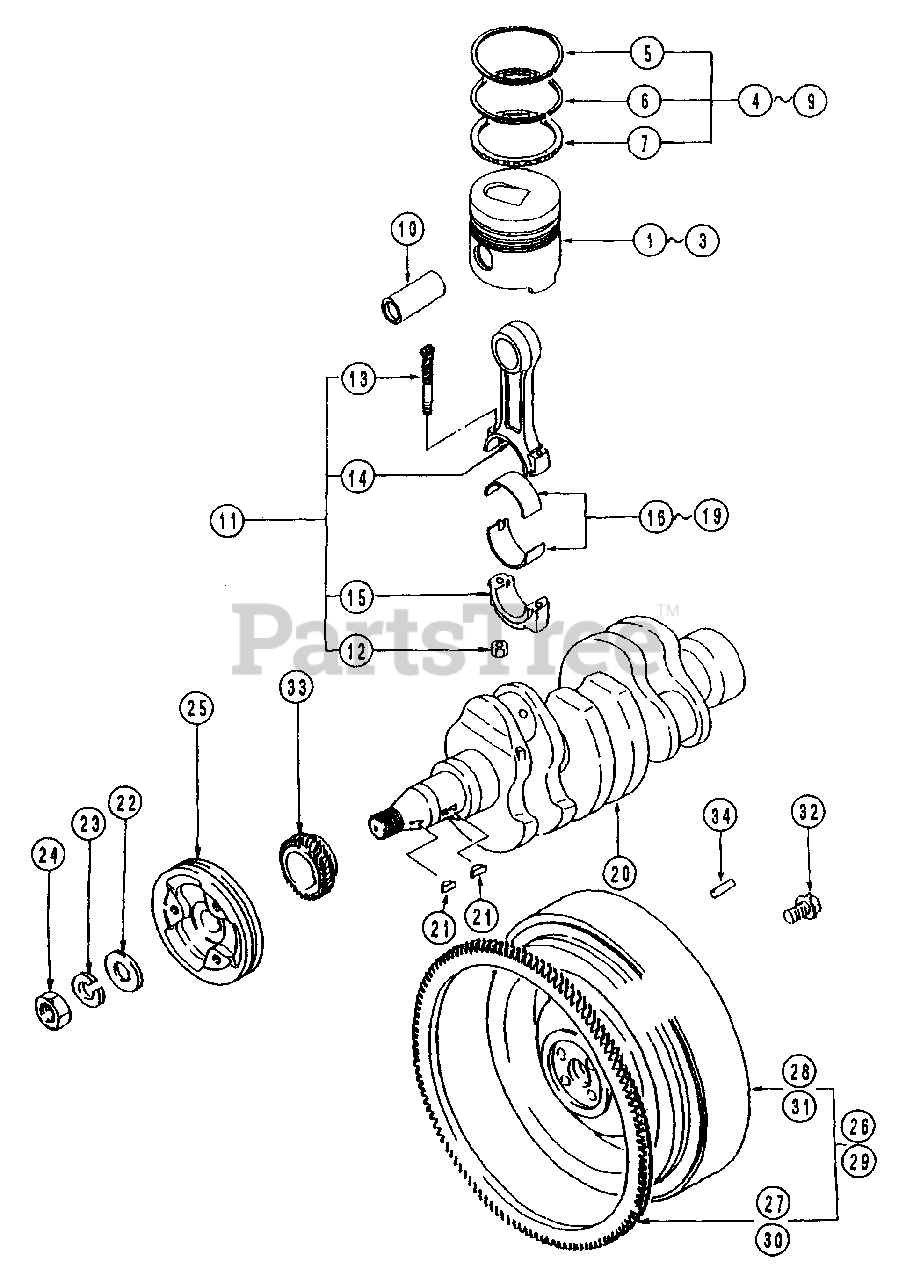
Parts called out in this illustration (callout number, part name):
2	Piston .25mm
4	Ring Set, Piston STD
5	Ring, Piston No.1
6	Ring, Piston No.2
7	Ring, Ass'y, Oil
8	Ring Set, Piston .25mm o/s
9	Ring Set, Piston .50mm o/s
11	Rod Ass'y, Connecting
13	Bolt, Connecting
14	Con-Rod
15	Cap,Connecting Rod
16	Metal Set, Con-Rod STD
17	Metal Set, Con-Rod .25
18	Metal Set, Con-Rod .50
19	Metal Set, Con-Rod .75
20	Crankshaft
21	Key, Woodruff
22	Washer, Plain
23	Washer, Spring
25	Pulley, Crankshaft
26	Flywheel Ass'y
28	Flywheel
29	Flywheel Sub Ass'y
30	Flywheel Sub Ass'y
31	Gear, Ring
33	Gear, Crankshaft
34	Pin, Dowel
